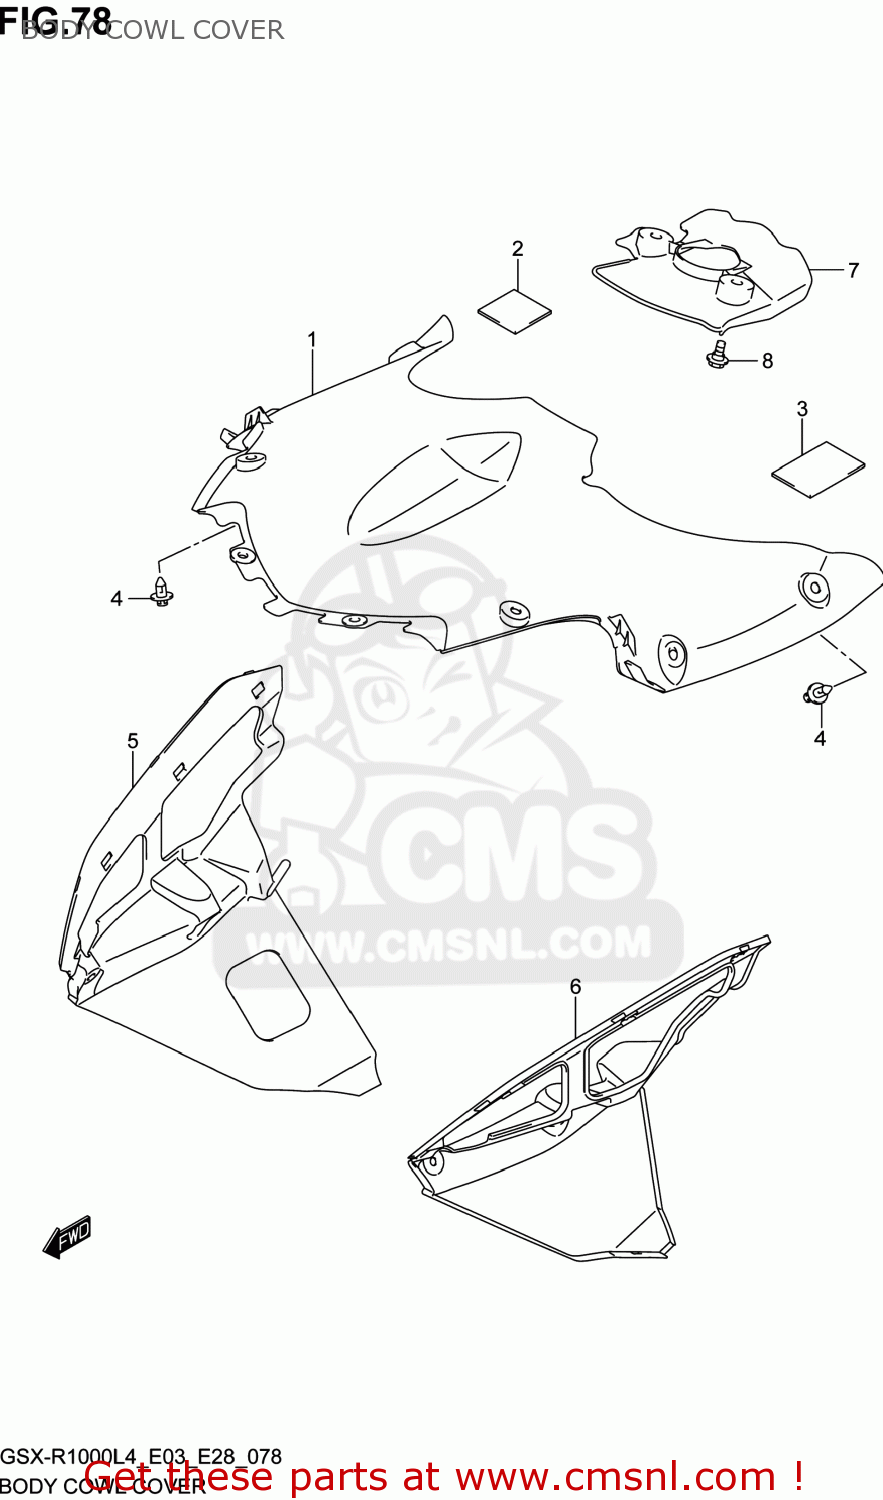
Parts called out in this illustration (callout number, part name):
1	COVER,BODY COWLING
2	PROTECTOR,BATTERY
3	COVER
4	CLIP(BLACK)
5	COWLING,UNDER INNER,R
6	COWLING,UNDER INNER,L
7	COVER,LWR BRACKET
8	BOLT(6X12)
